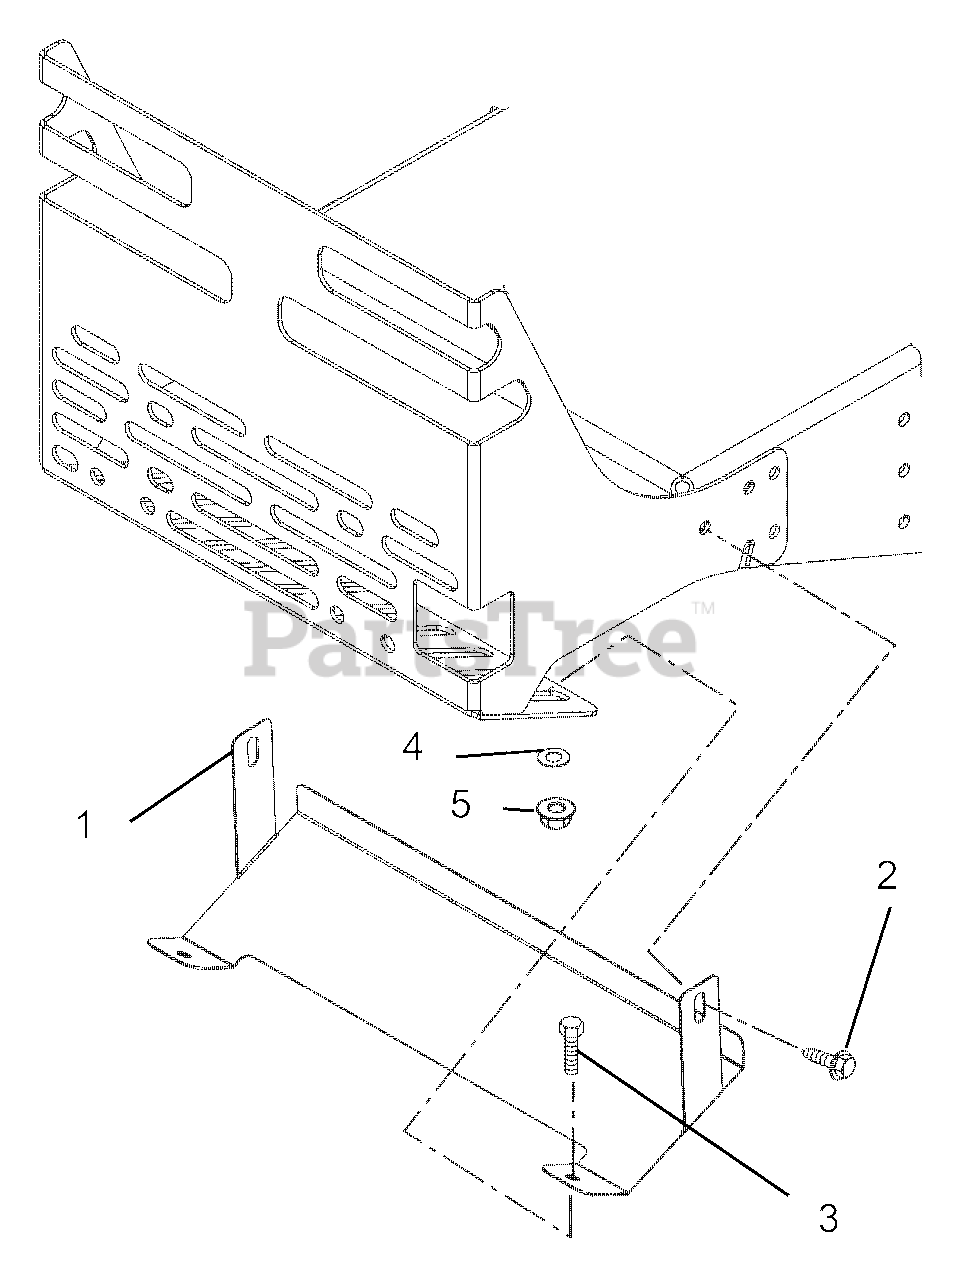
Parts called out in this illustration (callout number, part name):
1	Shield - Heat - CZ (Kit 591008)
2	.38-16 x .50" Hex Washer Head Tap Screws
3	.38-16 x 75 Hex Bolt
4	.438" x 1.00" x .083" Flat Steel Washer
5	.38-16 top Flange Lock Nuts
